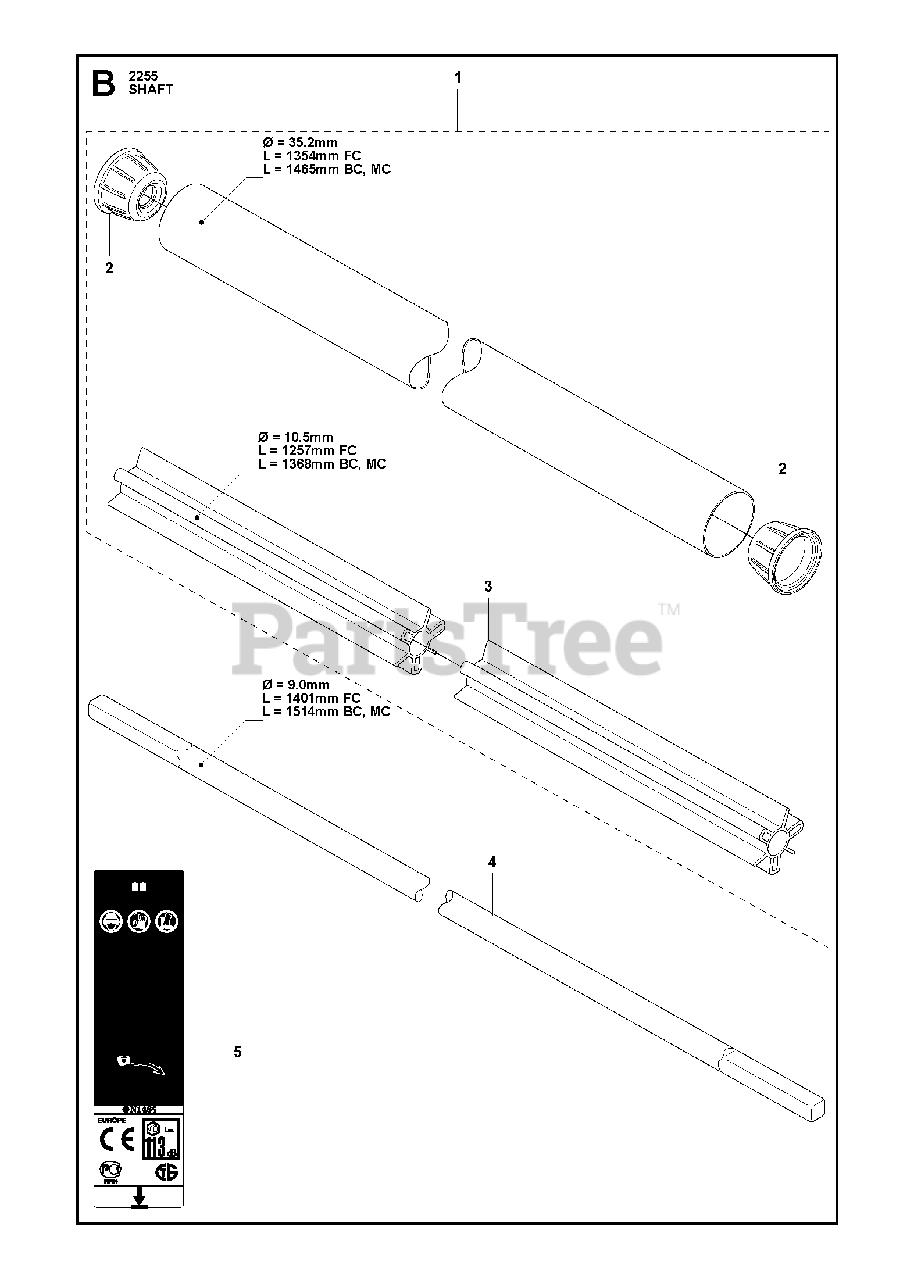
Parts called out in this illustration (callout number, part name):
1	TUBE ASSY
2	RP SPACER
3	BEARING SHAFT
4	DRIVE SHAFT
